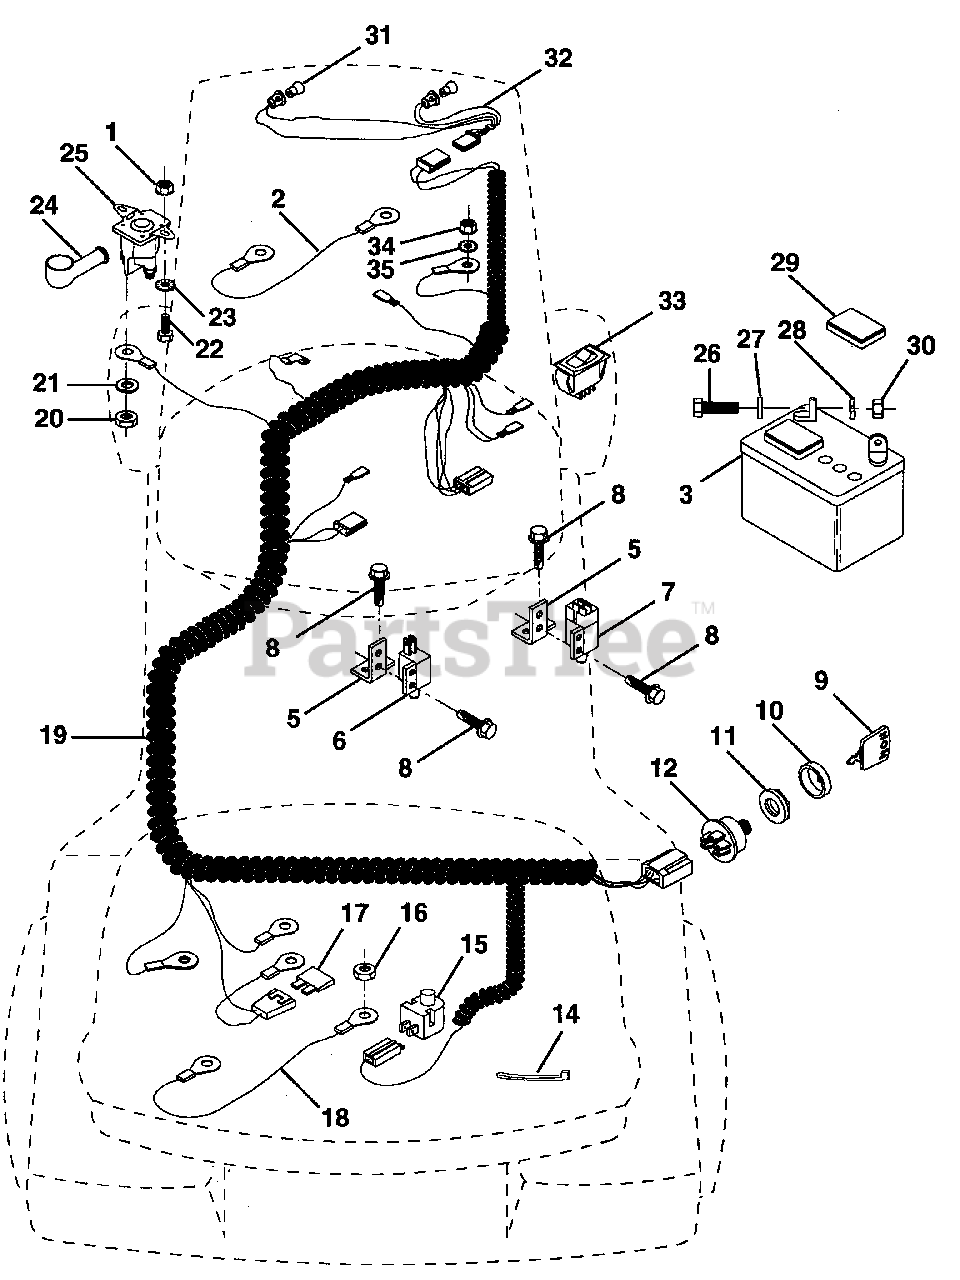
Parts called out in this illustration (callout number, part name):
1	Nut, Hex, Keps 1/4-20 UNC (AYP part number)
2	Assembly, Cable (AYP part number)
3	Battery (AYP part number)
5	Bracket, Switch (AYP part number)
6	Switch, Interlock (AYP part number)
7	Switch, Interlock (AYP part number)
8	Screw, Hex Head, Tapping #10-24 x 1/2 (AYP part number)
9	Key, Molded (AYP part number)
10	Cover, Key, Ignition (AYP part number)
11	Nut, Ignition (AYP part number)
12	Switch, Ignition (AYP part number)
14	Tie, Cable (AYP part number)
15	Switch, Plunger (AYP part number)
16	Nut, Keps 5/16-18 (AYP part number)
17	Fuse (AYP part number)
18	Assembly, Cable (AYP part number)
19	Harness, Ignition
20	Nut, Hex, Jam 1/4-20 (AYP part number)
21	Washer, Lock 1/4 (AYP part number)
22	Bolt, Hex 1/4-20 x 12 Grade 5 (AYP part number)
23	Washer, Lock, External Tooth 1/4 (AYP part number)
24	Cover, Terminal (AYP part number)
25	Solenoid (AYP part number)
26	Bolt, Hex Head 1/4-20 UNC x 3/4 (AYP part number)
27	Washer 9/32 x 5/8 x 16 Gauge (AYP part number)
28	Washer, Lock, Heavy Helical Spring 1/4 (AYP part number)
29	Cap, Battery (AYP part number)
30	Nut, Hex, Fin 1/4-20 (AYP part number)
31	Bulb (AYP part number)
32	Harness, Light Socket (AYP part number)
33	Switch, Light (AYP part number)
34	Nut, Hex, Keps 3/8-16 (AYP part number)
35	Washer, Lock, External Tooth 3/8 (AYP part number)
